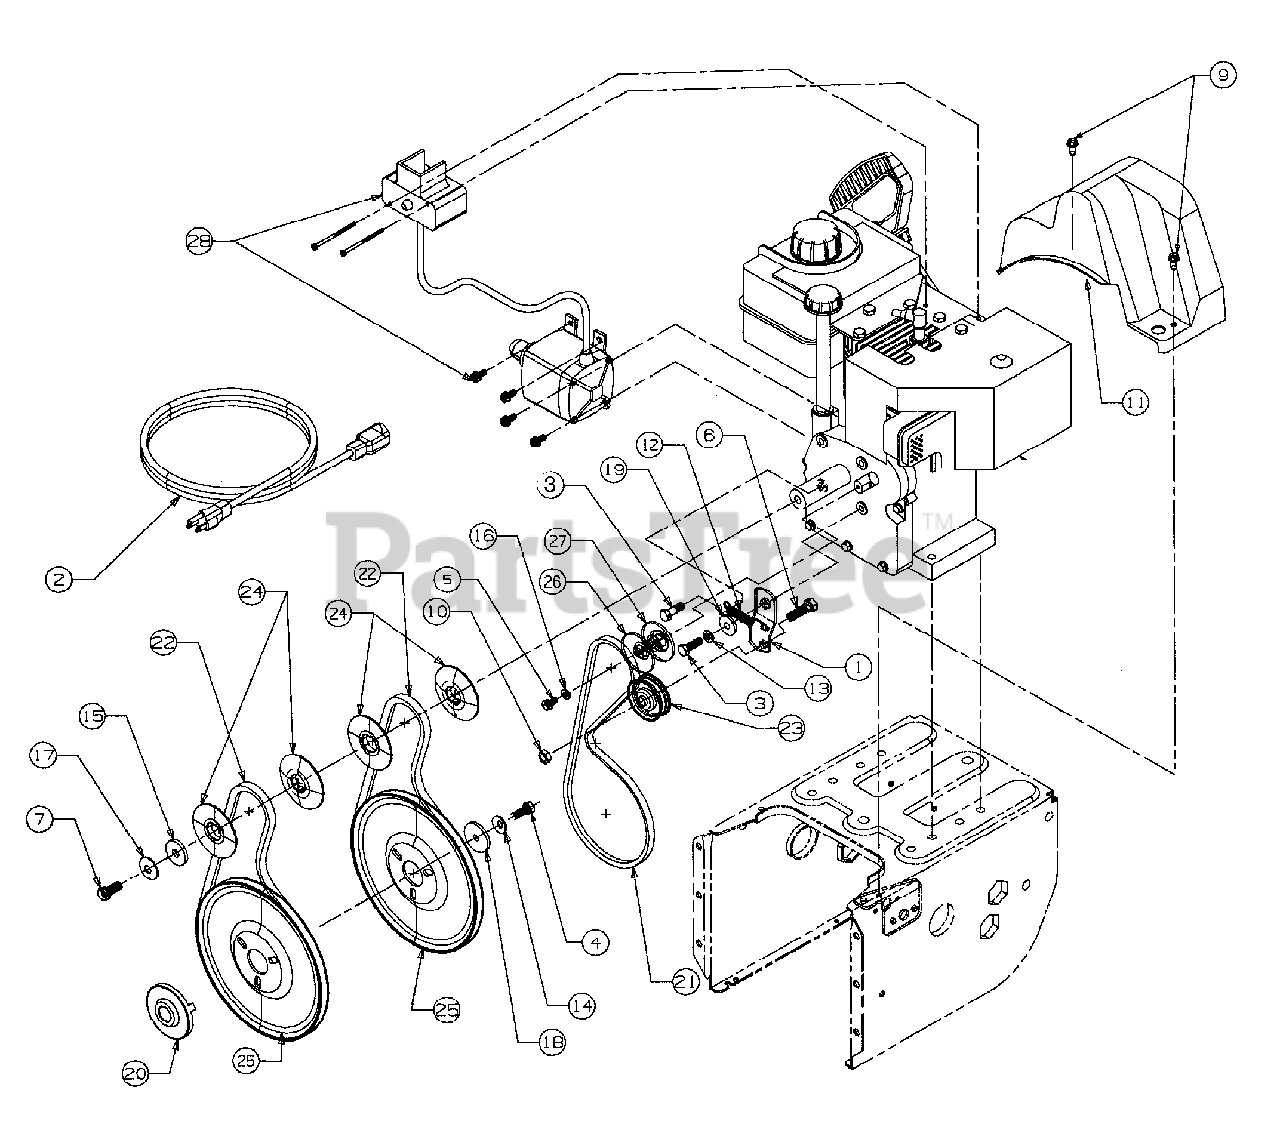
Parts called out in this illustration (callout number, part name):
3	Screw - Hex
4	Screw - Hex
5	Screw - Hex
6	Screw - Hex
7	Screw - Hex
9	Screw - Hex
10	Nut - Hex
11	Cover - Belt
12	Spring
13	Washer - Lock
14	Washer - Bell
15	Washer - Flat
16	Washer - Bell
17	Washer - Bell
18	Washer - Flat
19	Spacer
20	Adapter - Pulley
21	V-Belt
22	V-Belt
23	Idler - Flat
24	Pulley Half
25	Pulley - Auger
26	Pulley Half
27	Pulley Half
28	Electric Start Kit
